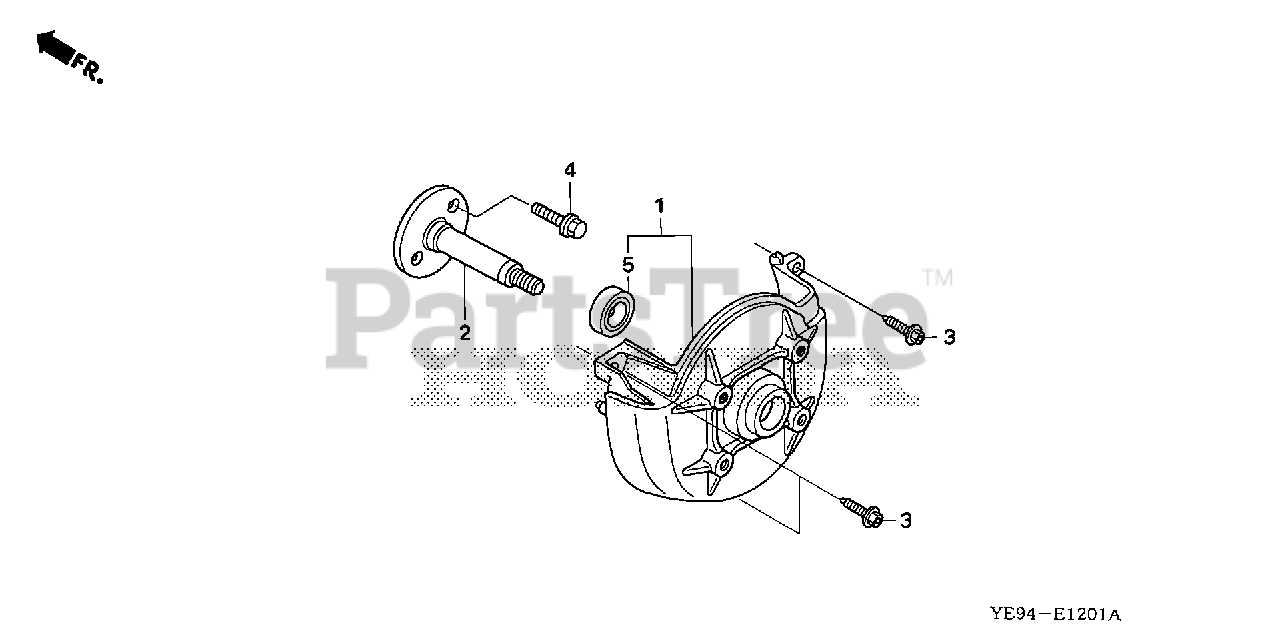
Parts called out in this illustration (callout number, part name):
1	COVER, FAN
2	SHAFT, P.T.O.
3	BOLT, SOCKET (5X20)
4	BOLT, FLANGE (6X22)
5	BEARING, RADIAL BALL (6001UU)
